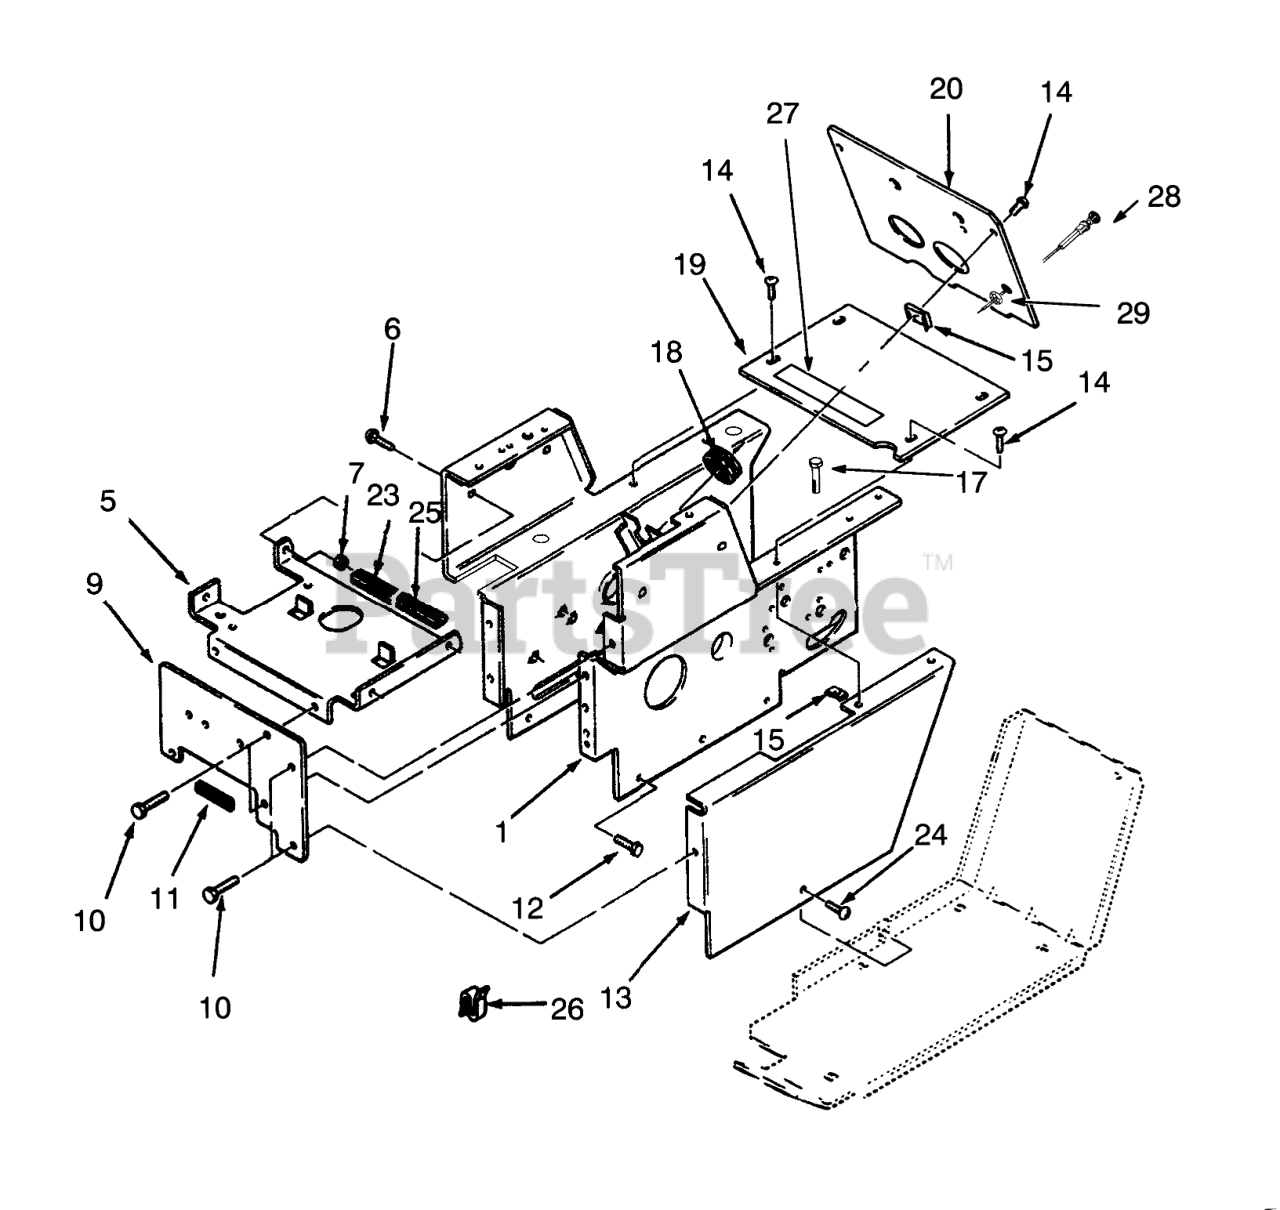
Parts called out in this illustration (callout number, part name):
1	Handstand
5	SUPORT-BATERYB
6	BOLT CARR. 5/16X1/2 BK
7	Nut
9	Front Plate
10	Bolt
11	EDGE TRIM 4IN OF 102896
12	Bolt
13	Cover-Side LH
14	SCREW-PPH
17	Bolt
18	GROMMET
19	Plate-Shift Cover, Top (Incl. Ref. #27)
20	Plate-Hood Stand
23	EDGE TRIM 5" OF 102896
24	SCREW-PPH
25	EDGE TRIM 2" 102896
26	SPEED CLIP
27	DECAL-DANGER
28	CONTROL-CHOKE
29	NUT-HEX PALNUT
